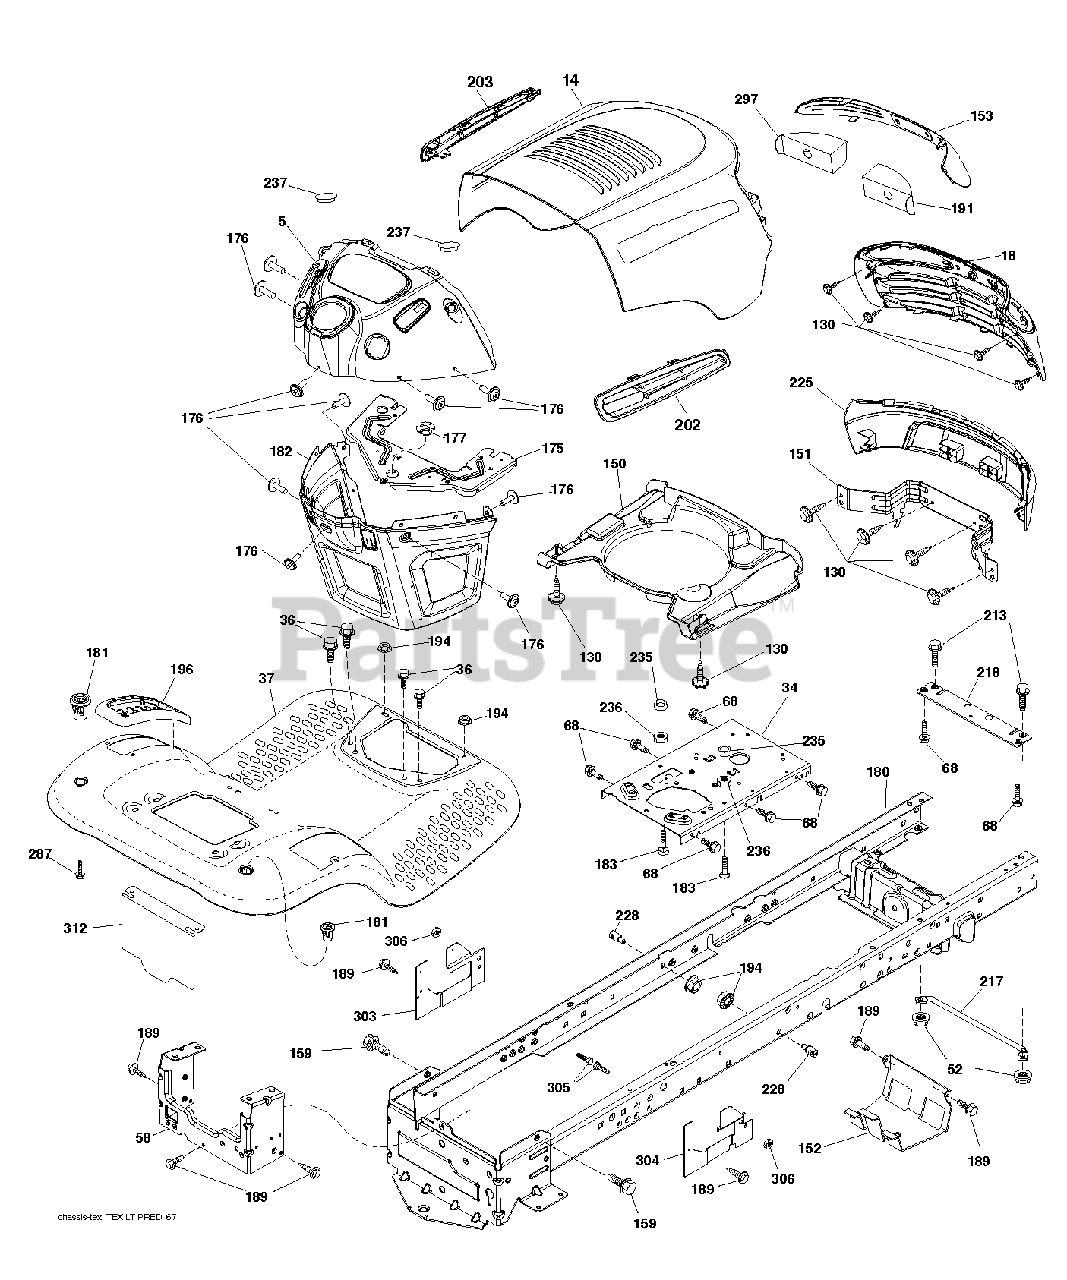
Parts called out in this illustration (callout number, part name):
5	DASH.PREDLT.CC.ICY.CK.N/SRV.BL
14	HOOD.PNT.PREDATOR.LT.TX.667
18	GRILLE.SVC.BASE.PREDATOR.LT428
34	Engine Welded Chassis Plate
36	SCREW 5/16"
37	FENDER.TLT.FS.W/NO CUPHLD.667
52	LOCKNUT
58	DRAWBAR UPPER 2PC SMALL FENDER
68	SCREW LT
130	SCREW.#10 X 0.750.BOS THREAD
150	DUCT.AIR.PREDATOR.LT.2.36"
151	BRACKET.PIVOT.ALPHA.LT
152	SHIELD BROWNING
153	LENS.PREDATOR.LT
159	SCREW, 3/8-16X3/4
176	SCREW.#10-24X5/8.RN.QU
177	BUSHING STEERING
180	CHASS.WLDMNT.TL.12GA/2P.48/54
181	FEND/FTRST.PCH.CPH.NFW
182	DASH.LWER.PREDATOR/HUSQ.LT
183	BOLT.5/16-18X1-1/4 FULL THD
189	SCREW
191	INSERT.REFLECT.PREDATOR.LT.RH
194	NUT LOCK HEX FLANGE 5/16-18
196	CONSOLE.ASM.DECKLFT.BL/RBT.TLT
203	VENT.SIDE.PRED.LT.LH.JONSERED
213	BOLT
217	ROD.PIVOT.HOOD
218	X-PIECE.HOOD.STOP.NON/
225	BUMPER.GRILLE.PRED.LT.JONS.505
228	STUD.FASTNER.W/ANTI-ROTATE
235	SPACER FENDER
236	NUT.CENTERLOCK.5/16-
237	PLUG.MOUNT.CARGO.BLK
297	REFLECTOR.INSERT.PRED.LH.LT
303	SHIELD CHASSIS LEFT
304	SHIELD CHASSIS RIGHT
305	BOLT
306	NUT LOCK FLG 3/8-16 UNC
312	SHIELD.PNT.DRAWBAR.FRENCH
